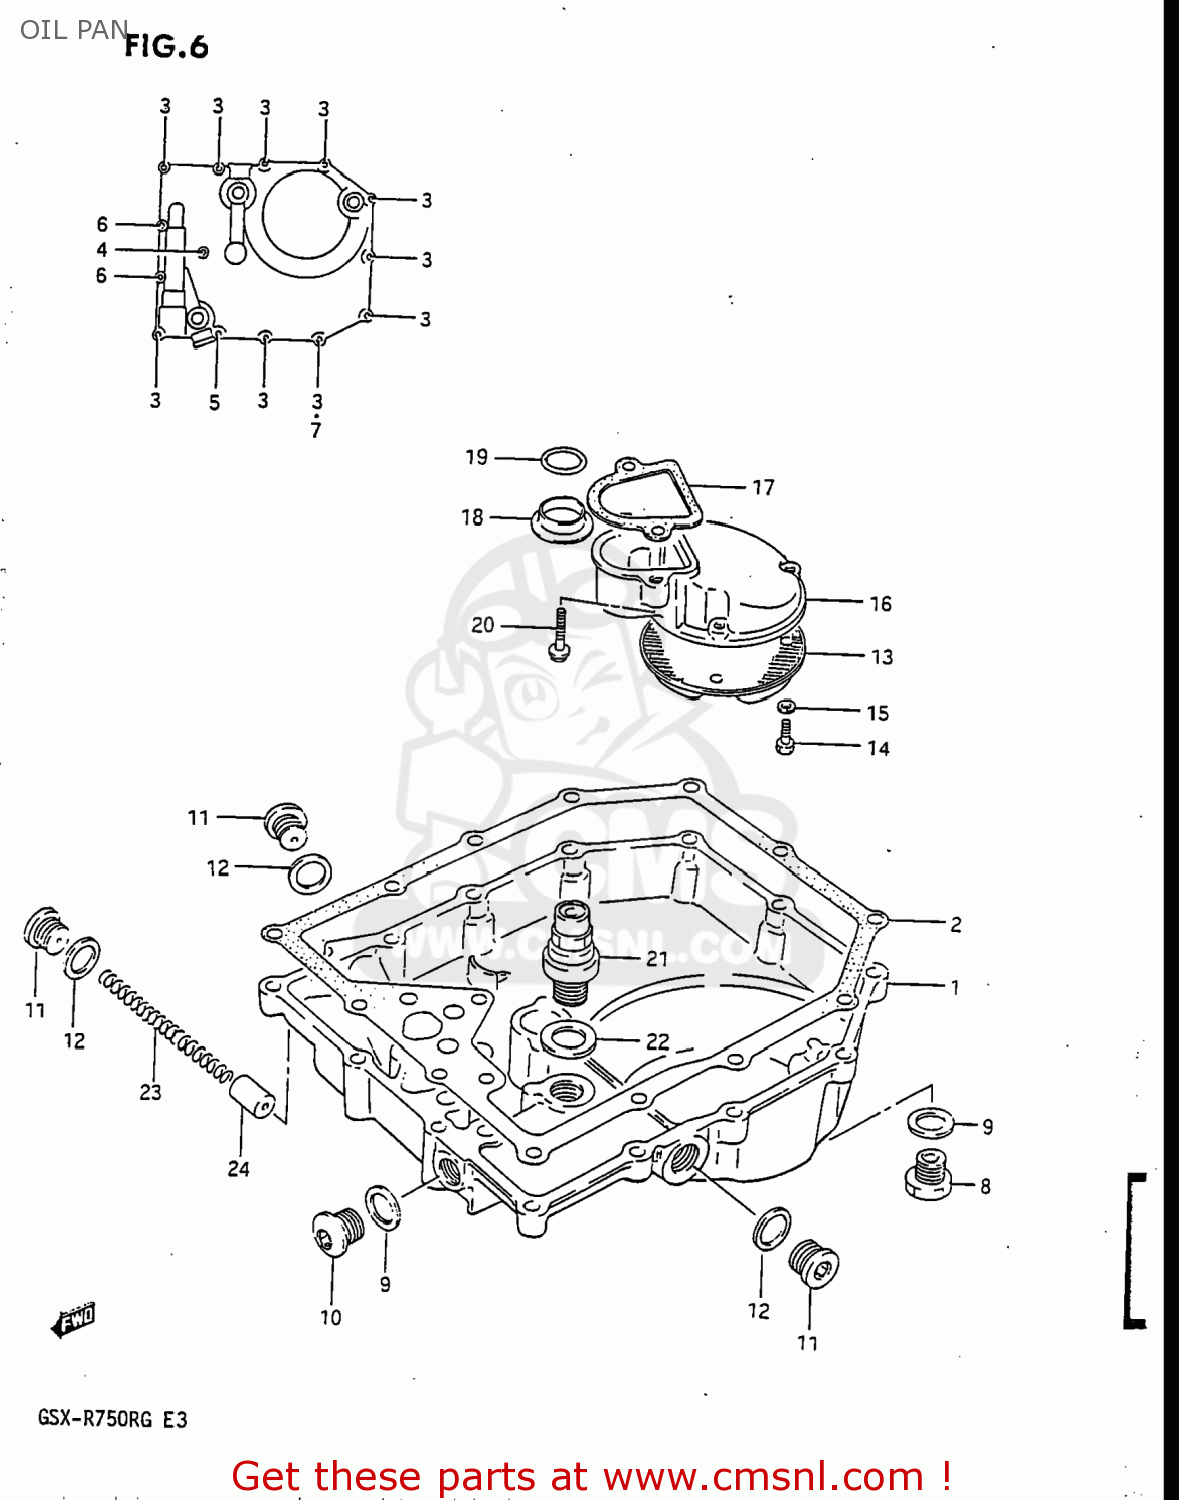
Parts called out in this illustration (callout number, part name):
1	PAN,OIL
2	GASKET,OIL PAN (NAS)
3	BOLT
4	BOLT
5	BOLT
6	BOLT
7	GASKET(5.8X13X1.2) (NAS)
8	PLUG
9	GASKET(14X19.2X2) (NAS)
10	PLUG
11	PLUG
12	GASKET(16X22X2) (NAS)
13	STRAINER,ENGINE OIL
14	BOLT
15	WASHER,LOCK
16	PROTECTOR,OIL STRAINER
17	GASKET,OIL STRAINER PROTECTOR (NAS)
18	GASKET,OIL OUTLET (NAS)
19	O RING(D:3.2,ID:17.8)
20	BOLT
21	VALVE ASSEMBLY,OIL RELIEF
22	GASKET(16X22X2) (NAS)
23	SPRING
24	PLUNGER,OIL CONTROLL
